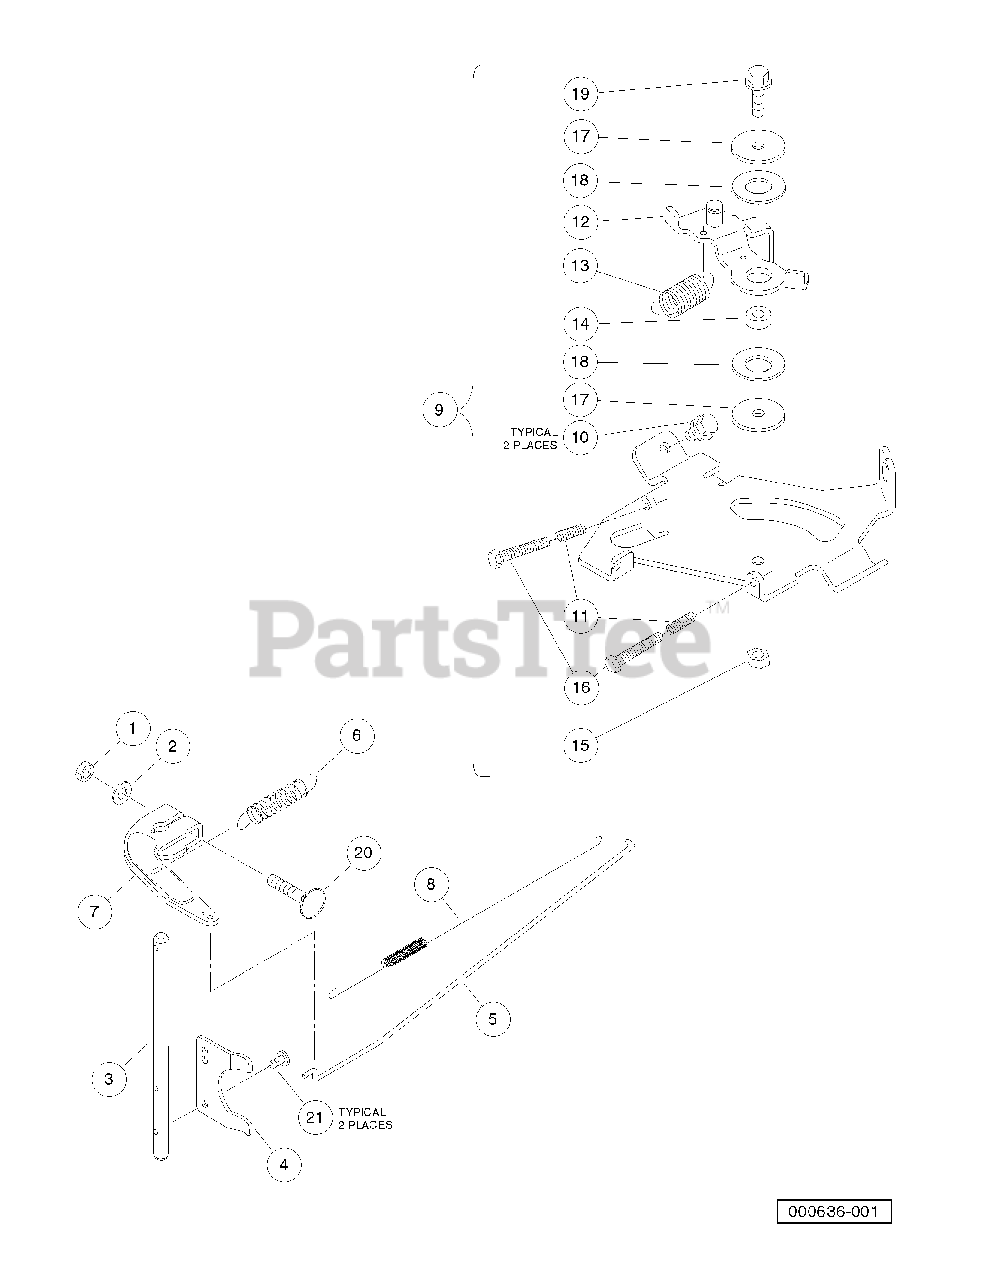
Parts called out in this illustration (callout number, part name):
2	Washer, M6 Flat
3	Shaft, Governor, Fh
4	Plate, Governor, Fh
5	Link, Arm, Governor, Fh
6	Spring, Governor, Fh
7	Arm, Governor, Shaft
8	Spring, Arm, Governor, Fh
9	Panel, Control, Complete, Fh
10	Bolt, Flg, M6 X 1.0 X 12
11	Spring, Fh
12	Lever, Governor, Control, Fh
13	Spring, Governor Return, Fh
14	Collar, Governor, Fh
15	Nut, Governor, Fh
16	Bolt, Speed Control, Fh
17	Washer, Governor, Lower, Fh
18	Washer, Governor, Middle, Fh
19	Bolt, Flanged, M6 X 20, Kaw
20	Bolt, M6 X 35, Kawasaki
21	Screw, Pan, Governor, Fh
